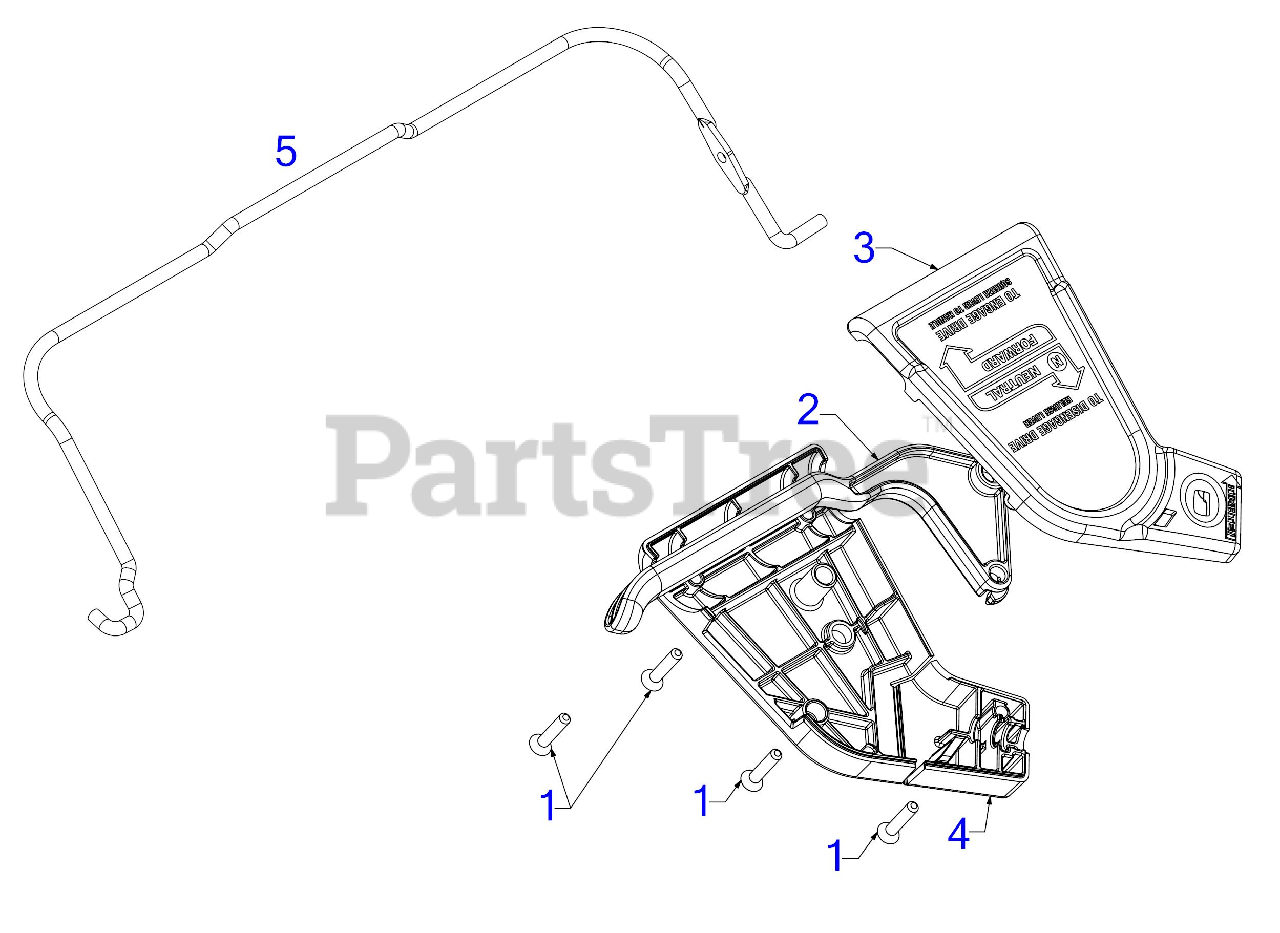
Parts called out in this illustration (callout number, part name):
1	SCREW #10-16 x 1.00
2	ENGAGEMENT LEVER
4	SQUEEZEBOX CONTROL COVER
5	OPERATOR BAIL
